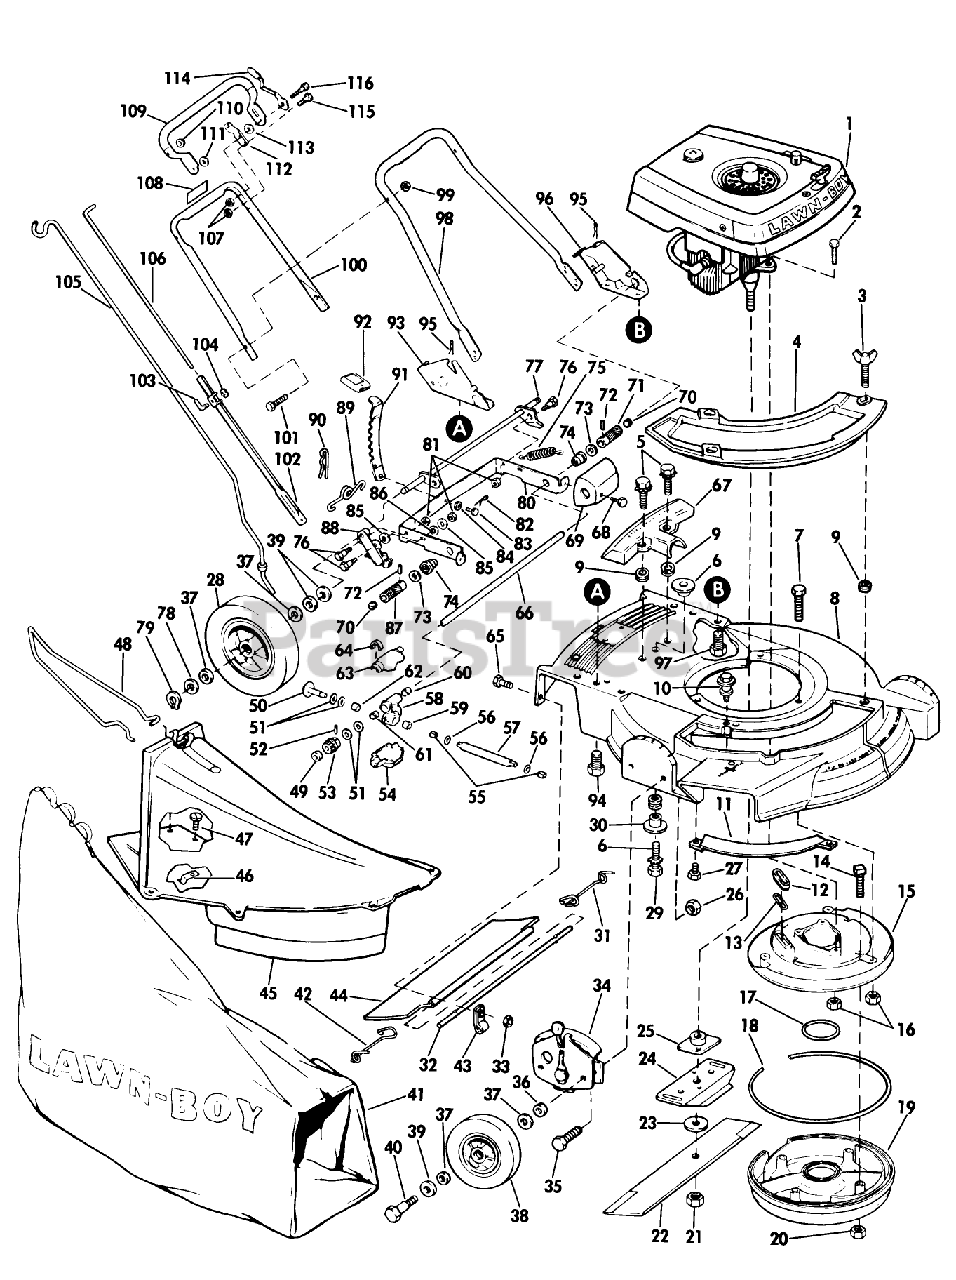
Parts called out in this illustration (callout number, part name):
2	BOLT F
3	WING SCREW LAWRE
5	SCREW SEMS TRM HEX HD
6	SPACER ECK PRES
7	SCREW V
11	BAR-TOE
12	SLEEVE
13	GASKET S
14	SCREW
16	NUT-LOCK F
18	Gasket Muffler (outside)
20	LOCKNUT E
21	NUT-BLADE
23	WASHER
25	PLATE AND COLLAR ASM
26	NUT
30	GROMMET
31	SPRIG T/SHLD ASOC
32	ROD 21" ADVANCE
36	WASHER WROUGHT
37	WASHER
39	SPACER
40	BOLT WHEEL
41	89802 LB WHOLE GOODS
42	SPRING;TRAILING SHIELD RH
43	CLAMP ROD KMC
49	WASHER
51	THRUST WASHER
52	ROLL PIN
55	BUSHING
56	O Ring
62	NEEDLE BEARING
63	GEAR COVER UPPER
67	COVER
69	GUARD
70	GREASE PLUG
72	PIN
75	SPRING
76	BOLT RB&W
78	SPACER
79	RET RING
81	STOP NUT
83	PIN
84	WASHER SPRING LAR
85	WASHER S
89	SPRING N.A.S
91	LEVER
92	KNOB
94	SCREW
95	HAIR PIN
97	SCREW
101	Screw
105	ROD GRASSBAG
106	ROD CONTROL
111	WASHER M
114	KNOB & SPRING
116	BOLT RB&W
